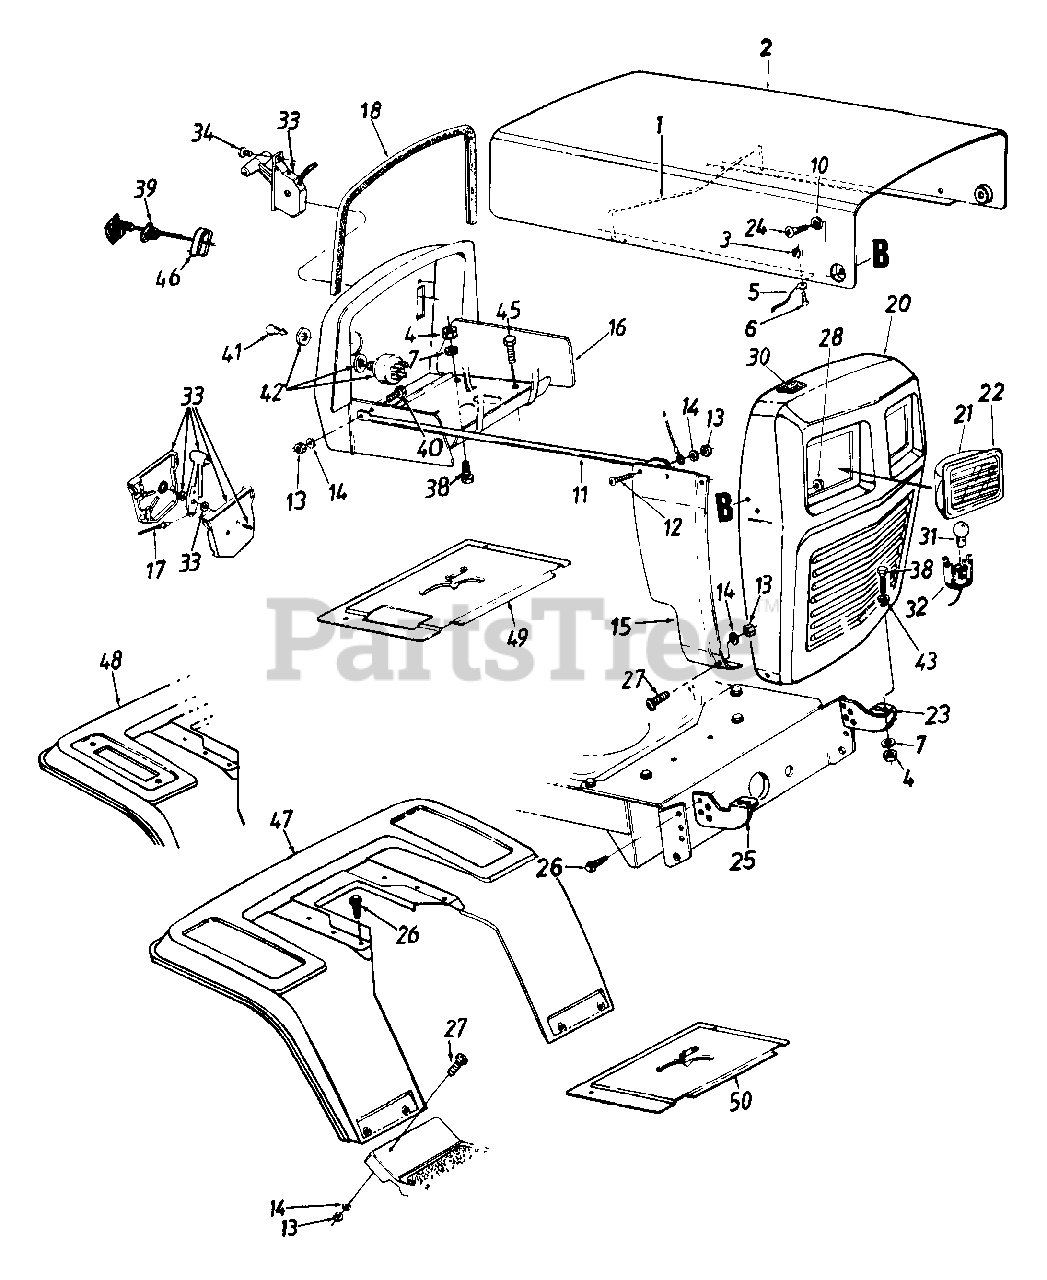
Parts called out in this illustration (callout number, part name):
1	Hood Spring
4	Hex Nut 5/16-18 Thd.
5	Hood Stop 7" Lg.
6	Truss Hd. Scr. #10-24 x 1/2"
7	L-Wash. 5/16" I.D.
10	Washer .39" I.D. x .62" O.D.
11	Grille Support Rod
12	Truss Hd. Scr. 1/4-20 x .75"
13	Hex Nut 1/4-20 Thd.
14	L-Wash. 1/4" I.D.
17	Throttle Control Wire - B&S
18	Molding Strip 31" Lg.
22	Headlight Lens
25	Mounting Brkt.- R.H.
26	Hex Wash Hd. AB-Tap Scr 5/16 x 75" Lg.
27	Carriage Bolt 1/4-20 x 2.0" Lg.
28	L-Nut 1/4-28 Thd.
30	Foam Strip 3/8 x 1-1/8 x 1-1/2
31	Bulb
32	Twist Lock Lamp Socket
33	Throttle Box Ass'y
34	Truss Mach. AB-Tap Scr #10 x .5" Lg.
38	Hex Bolt 5/16-18 x 75" Lg.
39	Choke Control 29" Lg.
40	Hex Bolt 1/4-20 x .62" Lg.
41	Ignition Key
42	Ignition Switch
43	Fl-Wash. .344" I.D. x 1" O.D.
45	Hex Wash. Hd B-Tap Scr. 5/16-18 x .5" Lg.
46	Choke Retainer
